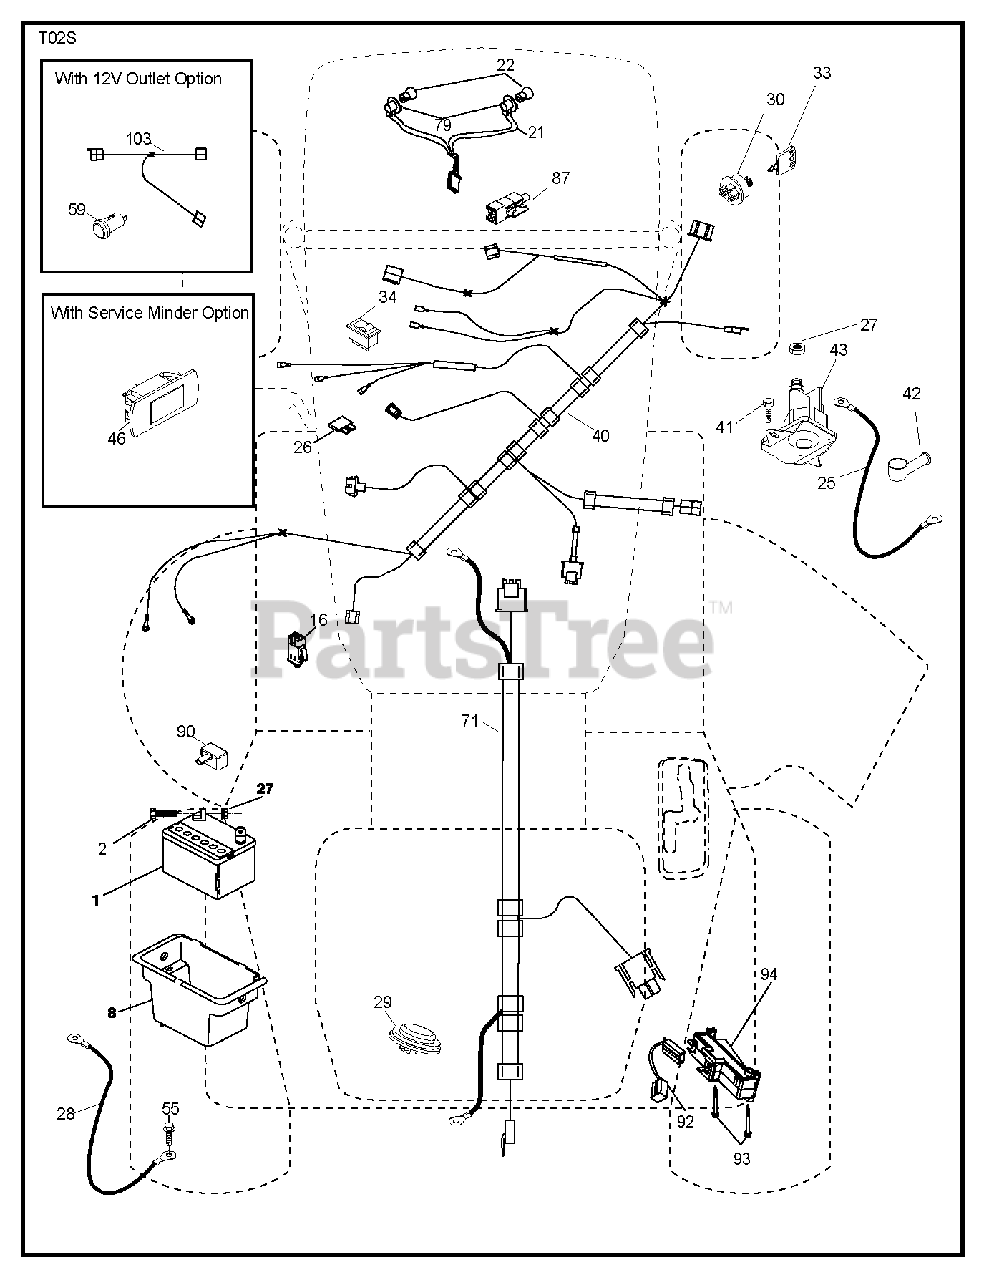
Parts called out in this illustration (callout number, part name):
2	BOLT LT
16	SWITCH INTERLOOK PUSH-IN
22	LIGHTBULB
25	CABLE STARTER
26	FUSE 20AMP
29	SWITCH.SEAT.DELTA.OPC.
30	IGNITION SWITCH
33	KEY/CHAIN.BLISTER.PACK.GEN.USA
34	SWITCH LT
43	SOLENOID.W/BRASS.PLUNG
79	BULB HOLDER ASM.
